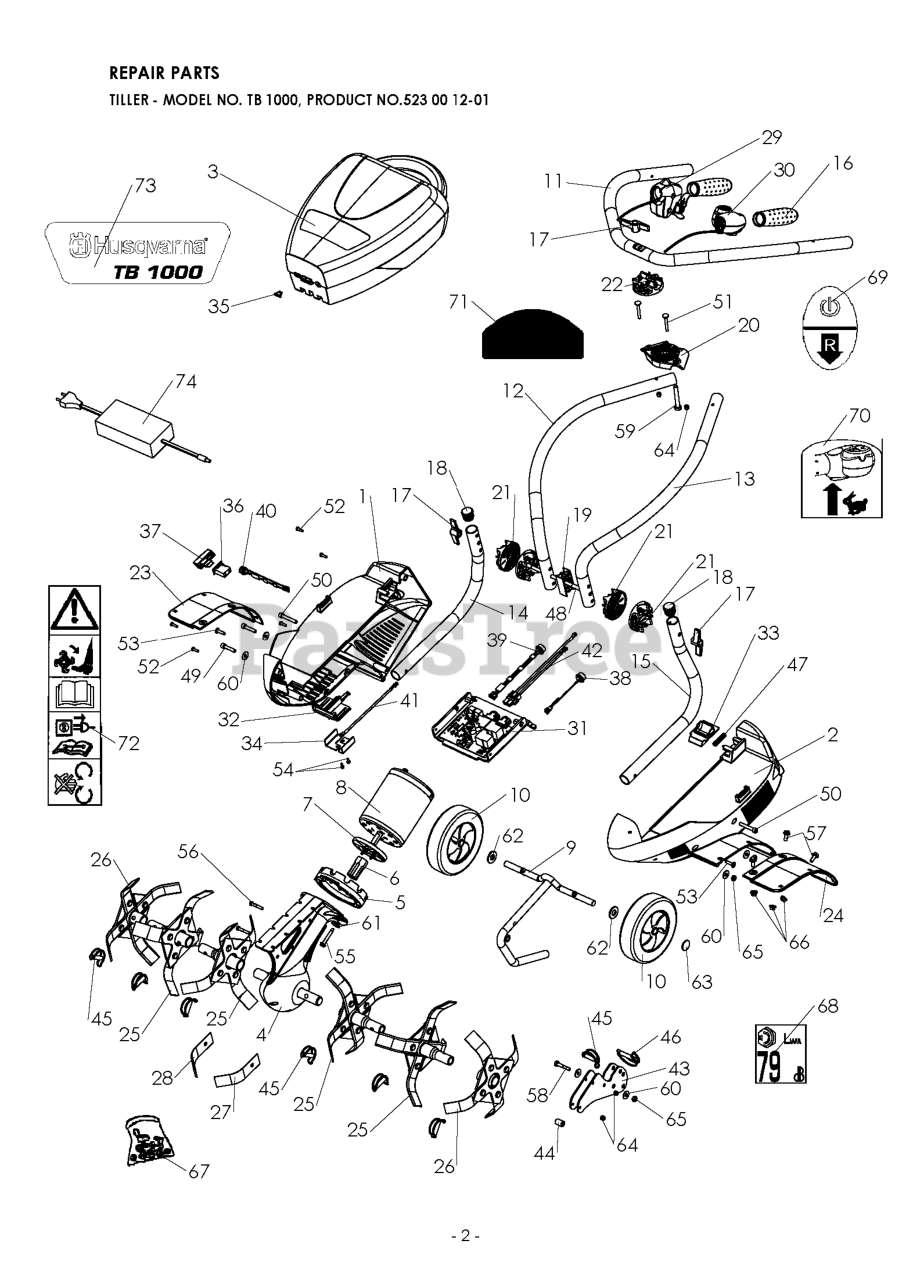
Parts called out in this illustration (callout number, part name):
4	TRANSMISSION
12	HANDLEBAR RIGHT
13	HANDLEBAR LEFT
14	HANDLEBAR RIGHT
15	HANDLEBAR LEFT
31	CONTROL BOARD
47	LOCKING SPRING
59	Screw HM 8x55 z cl 10.9
63	Starlock washer Ø12
65	Blocking nut M 6 Z
74	BATTERY CHARGER
